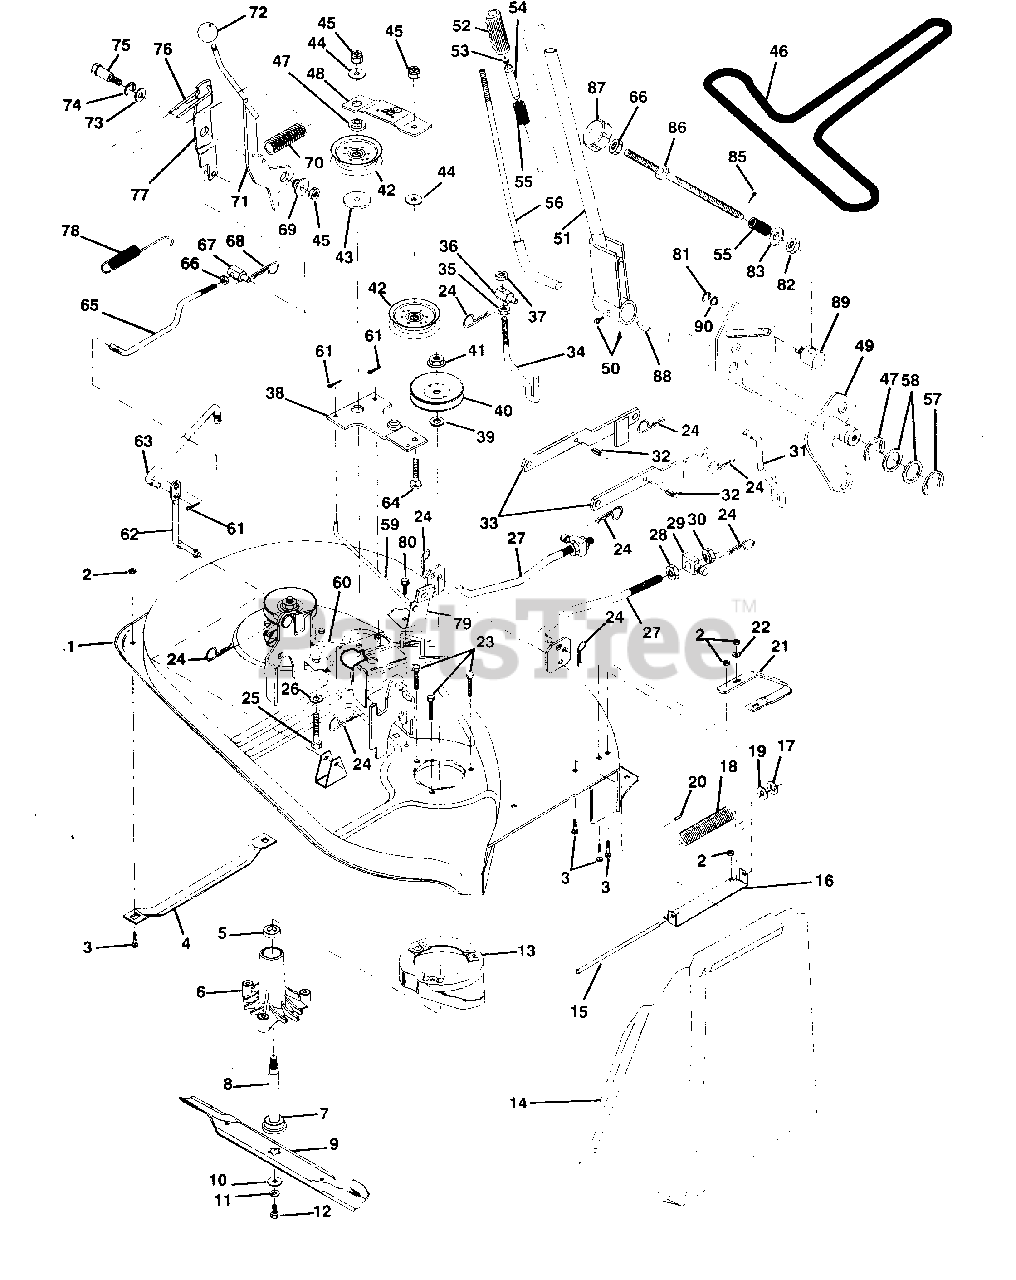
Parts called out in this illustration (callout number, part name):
1	Mower Asm. (AYP part number)
2	Nut, Crownlock 5/16-18
3	Bolt, Carriage 5/16-18 x 3/4
4	Runner, LH (AYP part number)
5	Bearing, Ball, Mandrel (AYP part number)
6	Mandrel Asm. (AYP part number)
7	Bearing, Ball (AYP part number)
8	Shaft, Mandrel, Mower, Vented (AYP part number)
9	Blade, Mower, High Performance (AYP part number)
10	Washer, Hard, Mower, Vented (AYP part number)
11	Washer, Lock Hvy 3/8 (AYP part number)
12	Bolt, Blade 3/8-24 x 1-1/4 Gr. 8 (AYP part number)
13	Stripper, Mower, Vented (AYP part number)
14	Shield, Deflector (AYP part number)
15	Rod, Hinge (AYP part number)
16	Bracket, Deflector, Mower (AYP part number)
17	Nut, Push (AYP part number)
18	Spring, Deflector (AYP part number)
19	Washer 11/32 x 5/8 x 16 Ga. (AYP part number)
20	Cap, Sleeve (AYP part number)
21	Runner, RH (AYP part number)
22	Washer 11/32 x 3/4 x 16 Ga. (AYP part number)
23	Bolt, Mandrel
24	Retainer, Spring (AYP part number)
25	Bolt, Carriage 3/8-16 x 2-1/4 (AYP part number)
26	Washer (AYP part number)
27	Link Asm., Front
28	Nut, Jam Hex 1/2-13 UNC (AYP part number)
29	Trunnion (AYP part number)
30	Nut, Crownlock 1/2-13 UNC (AYP part number)
31	Link, Lift, RH (AYP part number)
32	Pin, Spring 5/16-3/4 (AYP part number)
33	Arm, Suspension, Rear (AYP part number)
34	Link, Lift, LH (AYP part number)
35	Nut, Hex Jam ASF 7/16-20 UNF (AYP part number)
36	Trunnion, Lift (AYP part number)
37	Nut, Crownlock Jam 7/16-24 UNF (AYP part number)
38	Idler, Arm (AYP part number)
39	Washer, Spacer, Mower, Vented (AYP part number)
40	Pulley, Mandrel, Single (AYP part number)
41	Nut, Flangelock 9/16 (AYP part number)
42	Pulley, Idler, Flat (AYP part number)
43	Spacer, Retainer (AYP part number)
44	Washer 13/32 x 1 x 12 Ga. (AYP part number)
45	Nut, Crownlock 3/8-16
46	Belt (AYP part number)
47	Spacer Retainer (AYP part number)
48	Upper, Arm Idler (AYP part number)
49	Shaft Asm., Lift
50	Screw, Set, Hex Skt. 3/8-16 x 3/8 (AYP part number)
51	Lever, Lift (AYP part number)
52	Grip, Handle (AYP part number)
53	Button, Plunger (AYP part number)
54	Plunger, Lever, Lift (AYP part number)
55	Spring Compression (AYP part number)
56	Rod Asm., Lever (AYP part number)
57	Ring, E (AYP part number)
58	Washer 21/32 x 7/8 x 16 Ga. (AYP part number)
59	Rod, Brake RH (AYP part number)
60	Rod, Brake LH (AYP part number)
61	Pin, Cotter 3/32 x 3/4 (AYP part number)
62	Rod, Pivot (AYP part number)
63	Rod, Clutch, Secondary (AYP part number)
64	Bolt, Carriage 3/8-16 x 1-3/4 (AYP part number)
65	Rod, Clutch Primary (AYP part number)
66	Nut, Hex Jam 3/8-16 (AYP part number)
67	Trunnion 3/8-16
68	Spring, Retainer (AYP part number)
69	Bushing (AYP part number)
70	Spring (AYP part number)
71	Arm Asm., Clutch, Primary
73	Washer 25/32 x 1-5/8 x 16 Ga. (AYP part number)
74	Ring, Klip (AYP part number)
75	Bolt, Shoulder (AYP part number)
76	Keeper, Spring (AYP part number)
77	Arm, Clutch, Secondary (AYP part number)
78	Spring, Return (AYP part number)
79	Brake Asm., Mower, Vented (AYP part number)
80	Screw, Hex Thdrol 5/16-18 x 3/4
81	Ring, Klip (AYP part number)
82	Nut, Special (AYP part number)
83	Washer 13/32 x 5/8 x 16 Ga. (AYP part number)
85	Pin, Cotter 3/32 x 1/2 (AYP part number)
86	Rod, Adjust, Lift (AYP part number)
87	Knob, Adjust, Lift (AYP part number)
88	Key, Woodruff (AYP part number)
89	Trunnion
90	Washer 15/32 x 3/4 x 16 Ga. (AYP part number)
